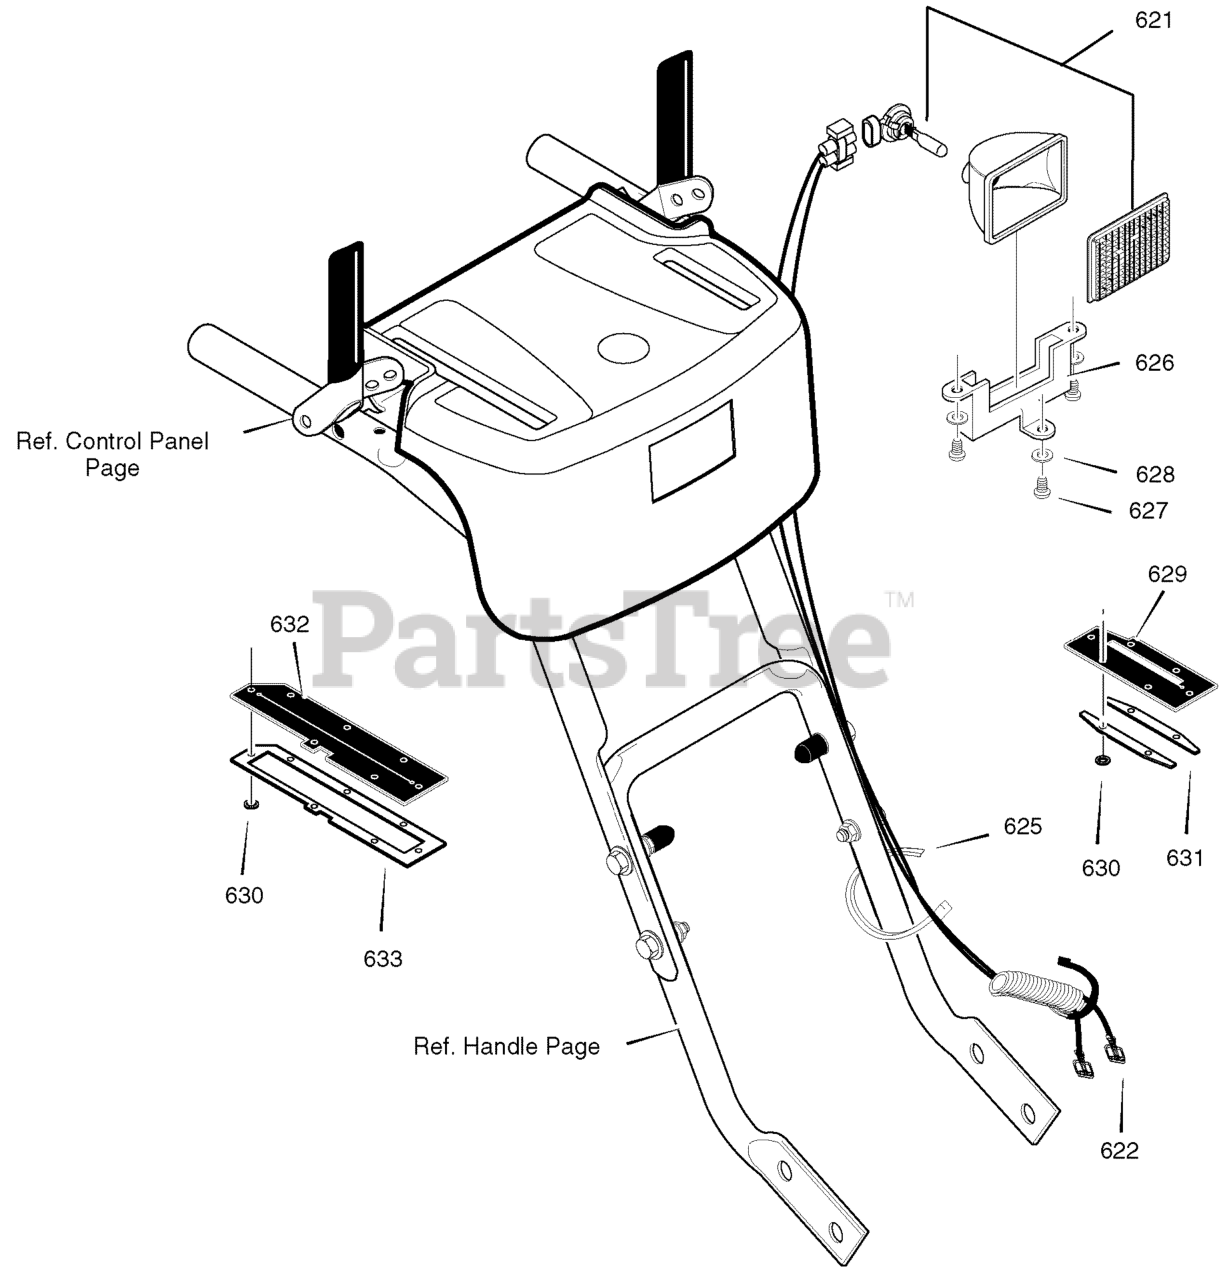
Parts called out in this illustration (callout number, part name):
621	LIGHT, HALOGEN
622	HARNESS, WIRE
625	TIE, CABLE
626	BRACKET, LIGHT
627	SCREW #8 X .50
628	WASHER, FLAT
629	COVER, CHUTE LEVER
630	NUT, PUSH
631	FRAME, COVER
632	COVER, SPEED LEVER
633	FRAME, SPEED COVER
